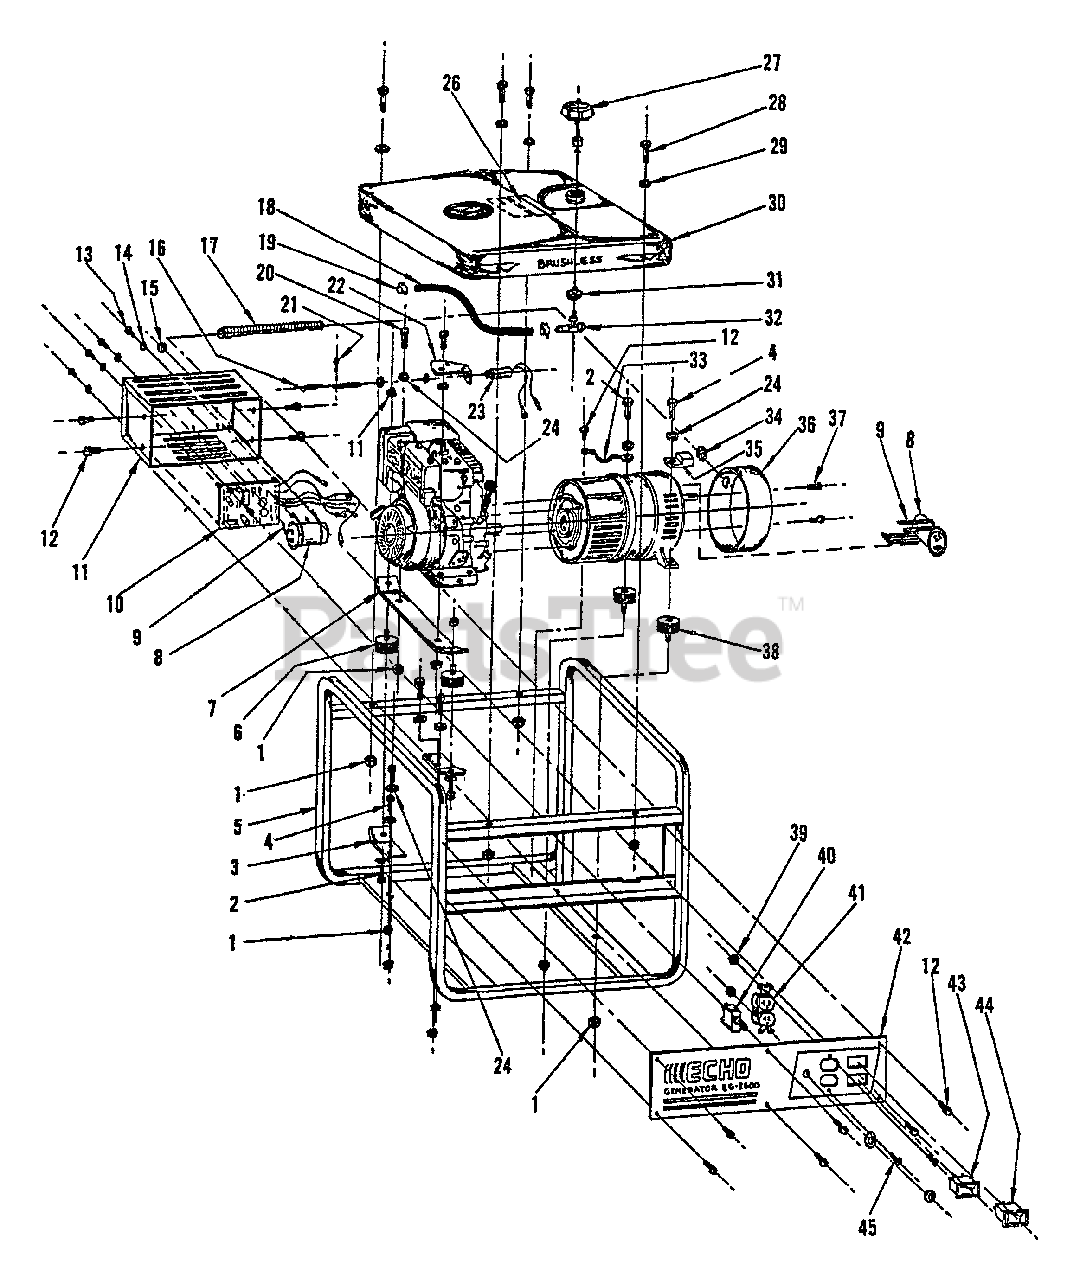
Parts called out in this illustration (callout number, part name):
1	LOCKNUT - 5/16-18
2	5/16-18×5/8 HHS
3	BRACKET, FOCUS
4	5/16-18×7/8 HHS
5	FRAME
6	ISOLATOR, VIBRATION
7	RAIL, FOCUS
8	CAPACITOR - 50UF 370V
9	TIE, CABLE
10	CIRCUIT, ECHO-MIZER
11	BOX, CONTROL
12	SCREW - 10-24
13	6-32×1/4 RHS
14	WASHER, LOCK
15	GROMMET
16	SPRING, ECHO-MIZER
17	CONDUIT PIPE
18	LINE, FUEL - 24"
19	CLAMP
20	BOLT - 5/16-18×1-1/2"
21	BRACKET, SOLENOID
22	PIN, COTTER
23	SOLENOID ASSY
24	WASHER, LOCK 5×16
26	LABEL - SAFETY
27	CAP, FUEL
28	HHS 5/16-18×1.75
29	LOCKWASHER - 5/16"
30	TANK, FUEL - 3.5 GALLON
31	GROMMET
32	VALVE, FUEL TANK
33	LEAD - GROUND
34	GROMMET
35	LUG, GROUND - 1/0-14 CU/AL
36	COVER, END
37	SCREW - 10-24 -- SLOT HEAD
38	ISOLATOR, VIBRATION
39	NUT - 8-32 -- KEPS
40	BREAKER, CIRCUIT - 15A/250V
41	DUPLEX, 15A/125V
42	PANEL, SILKSCREENED
43	SWITCH, ECHO-MISER
44	SWITCH, IGNITION
45	8-32×3/8 RHS
